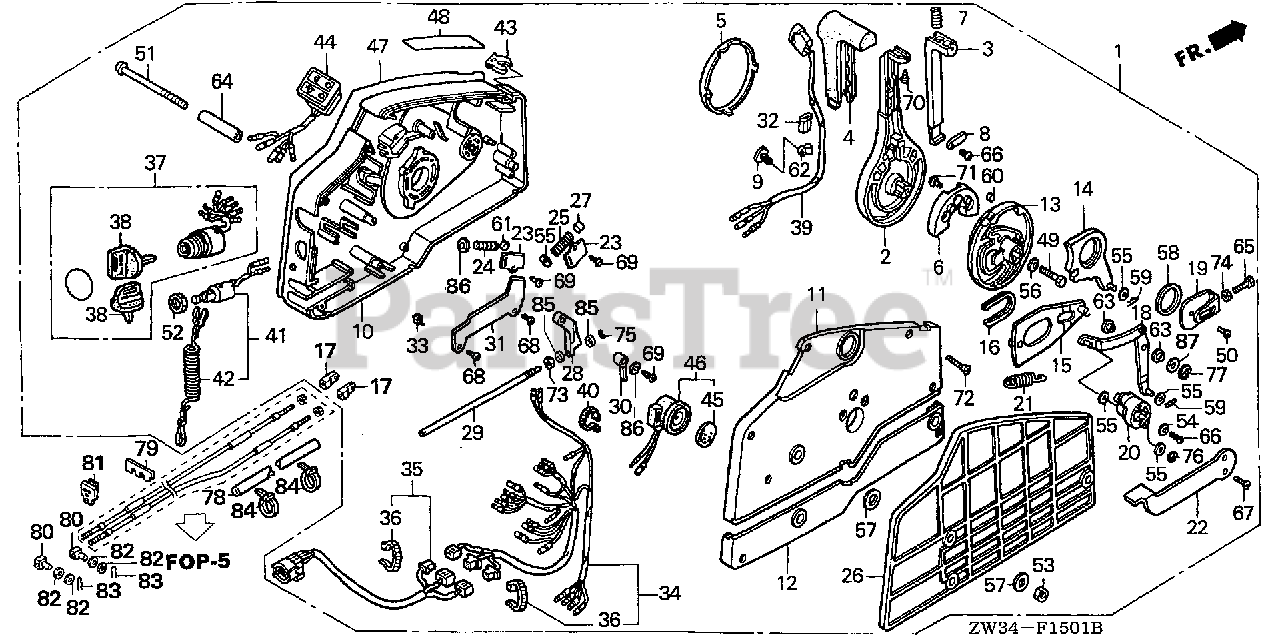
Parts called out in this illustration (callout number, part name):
1	BOX ASSY., REMOTE CONTROL (NHK MEC)
2	HANDLE, REMOTE CONTROL
3	LEVER, HANDLE LOCK
4	GRIP, REMOTE CONTROL HANDLE
5	CAP, HANDLE
6	BLOCK, NEUTRAL LOCK
7	SPRING, REMOTE CONTROL HANDLE
8	PLATE, LEVER SETTING
9	CLAMP, HARNESS
10	HOUSING, REMOTE CONTROL BOX (A)
11	HOUSING, REMOTE CONTROL BOX (B)
12	HOUSING, REMOTE CONTROL BOX (C )
13	WHEEL, CONTROL
14	ARM, SHIFT LINK
15	PLATE, SLIDING
16	COLLAR, SLIDING PLATE
17	PIVOT, SHIFT
18	ARM, LINK JOINT
19	BRACKET, LINK JOINT
20	WHEEL, ACCELERATOR
21	SPRING, ACCELERATOR WHEEL
22	LEVER, IDLE
23	PLATE, SPRING SETTING
24	SPRING, SHIFT CLICK
25	SPRING, CHOKE RETURN
26	SPACER, REMOTE CONTROL BOX
27	SPACER, CLICK SPRING
28	BLOCK, THROTTLE FRICTION
29	BOLT, FRICTION
30	SPACER, NEUTRAL SWITCH
31	CLAMP, POWER TILT CORD
32	PIPE, HARNESS GUIDE
33	SPACER, CABLE CLAMP
34	CABLE ASSY., REMOTE CONTROL (B) Use from Frame SN 1300029.
35	CABLE ASSY., SWITCH PANEL
36	TIE, CABLE (NATURAL 2.4X92) Use up to Frame SN 1300359.
37	SWITCH ASSY., COMBINATION DUAL QTY = (2) (SINGLE)
38	KEY ASSY., COMBINATION SWITCH (35100-ZV5-003 ONLY) DUAL QTY = (4) (SINGLE)
39	SWITCH ASSY., POWER TRIM-TILT
40	BAND (BLACK 3.5X140)
41	SWITCH ASSY., EMERGENCY STOP
42	WIRE, EMERGENCY (SINGLE) (DUAL)
43	CLIP, EMERGENCY LOCK
44	LAMP ASSY., INDICATION (2-LED)
45	PLATE, TURN SIGNAL BUZZER DUAL QTY = (2) (SINGLE)
46	BUZZER, WARNING DUAL QTY = (2) (SINGLE)
47	PLATE, REMOTE CONTROL (CAUTION=SILVER)
48	MARK, FAST IDLE
49	BOLT, FLANGE (8X35) Use from Frame SN 4800713.
50	SCREW, PAN (6X10)
51	SCREW (6X95)
52	NUT, HEX. (16MM) DUAL QTY = (2) (SINGLE)
53	NUT, HEX. (6MM)
54	WASHER, PLAIN (5MM)
55	WASHER, PLAIN (6MM) Use from Frame SN 4800713.
57	WASHER (6MM)
58	WASHER (28MM)
59	PIN, LOCK (6MM)
60	PIN (6X6)
61	ROLLER, CLICK
62	CLIP, WIRE HARNESS (6.3MM)
63	COLLAR, LINK JOINT
64	COLLAR, DISTANCE (6X10X43.5)
65	BOLT, HEX. (5X16)
66	SCREW, PAN (5X10)
67	SCREW, FLAT (5X12) Use from Frame SN 4800713.
68	SCREW, TAPPING (5X8) (FOR SILVER MUFFLER)
69	SCREW, TAPPING (5X10)
70	SCREW, TAPPING (5X12)
71	SCREW, TAPPING (6X16)
72	SCREW, TAPPING (5X25)
73	NUT, HEX. (6MM)
74	NUT, HEX. (5MM)
75	E-RING (3MM)
76	E-RING (4MM)
77	E-RING (7MM)
78	TUBE, CORRUGATED (28MM)
79	PLATE, REMOTE CONTROL CABLE
80	PIVOT, SHIFT
81	GROMMET, CASE (LOWER) (A)
82	WASHER, PLAIN (6MM) Use from Frame SN 4800713.
83	PIN, SPECIAL LOCK (6MM)
84	BAND, SELF-LOCK Use from Frame SN 3000253.
85	WASHER, PLAIN (4MM) Use from Frame SN 4800713.
86	WASHER, PLAIN (5MM)
87	WASHER, PLAIN (8MM) Use from Frame SN 4800713.
